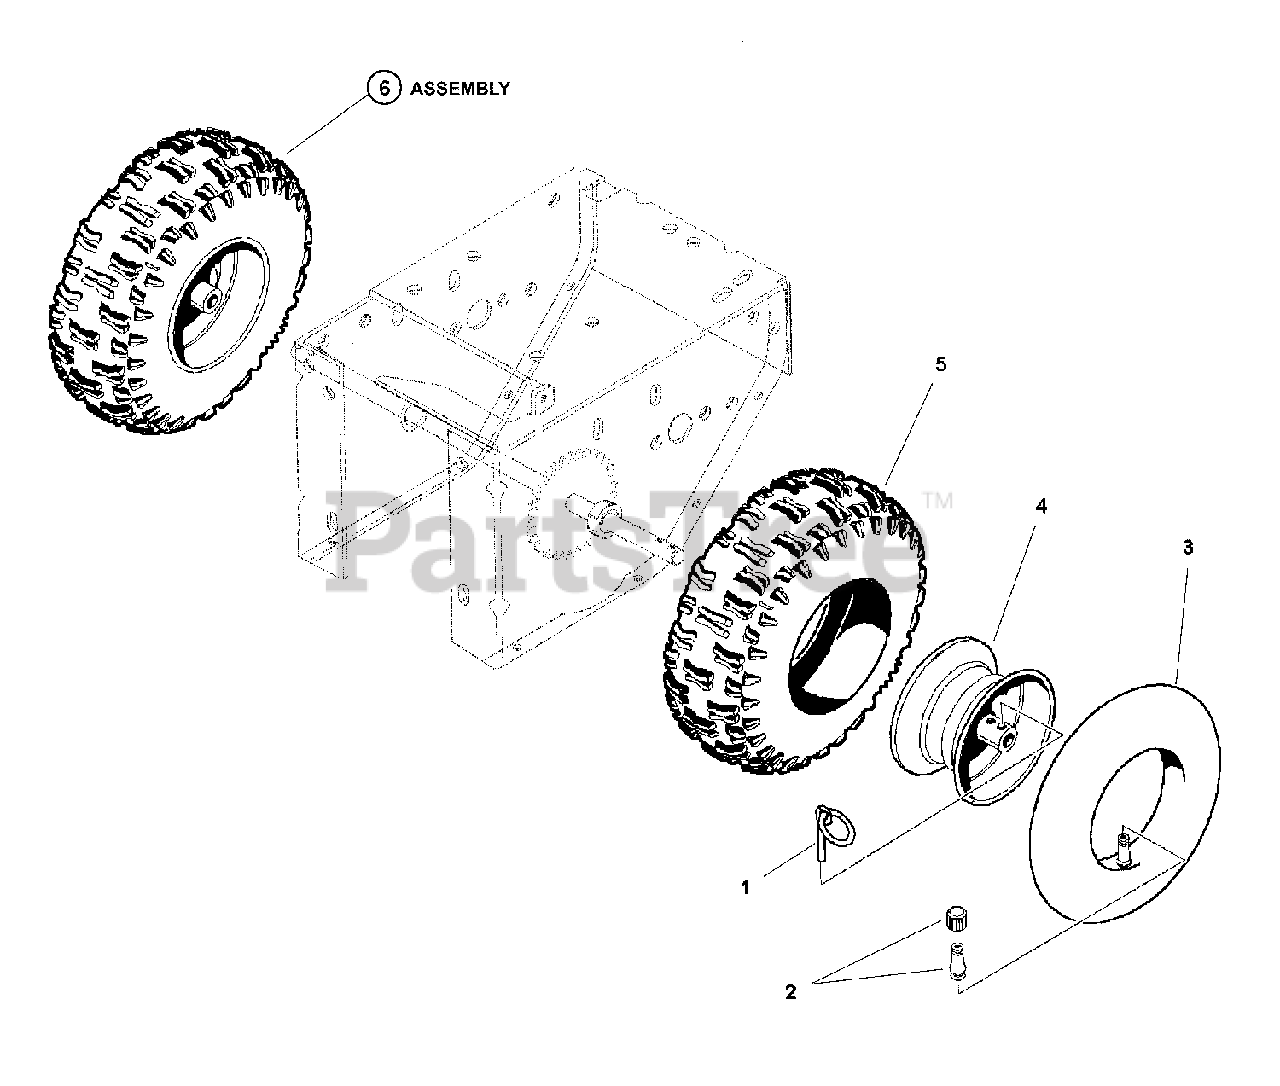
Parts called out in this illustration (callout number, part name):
1	KLIK- PIN, .310 ID x 1-3/4" Long
2	VALVE STEM AND CAP
3	TUBE, Tire
4	RIM, 6 x 3.25 (Weldment)
5	TIRE, 15 x 5.00-6, 2 Ply, Carlisle Snow Hog
6	ASSY, Tire and Wheel, 15 x 5.00-6 Carlisle Sno Hog
